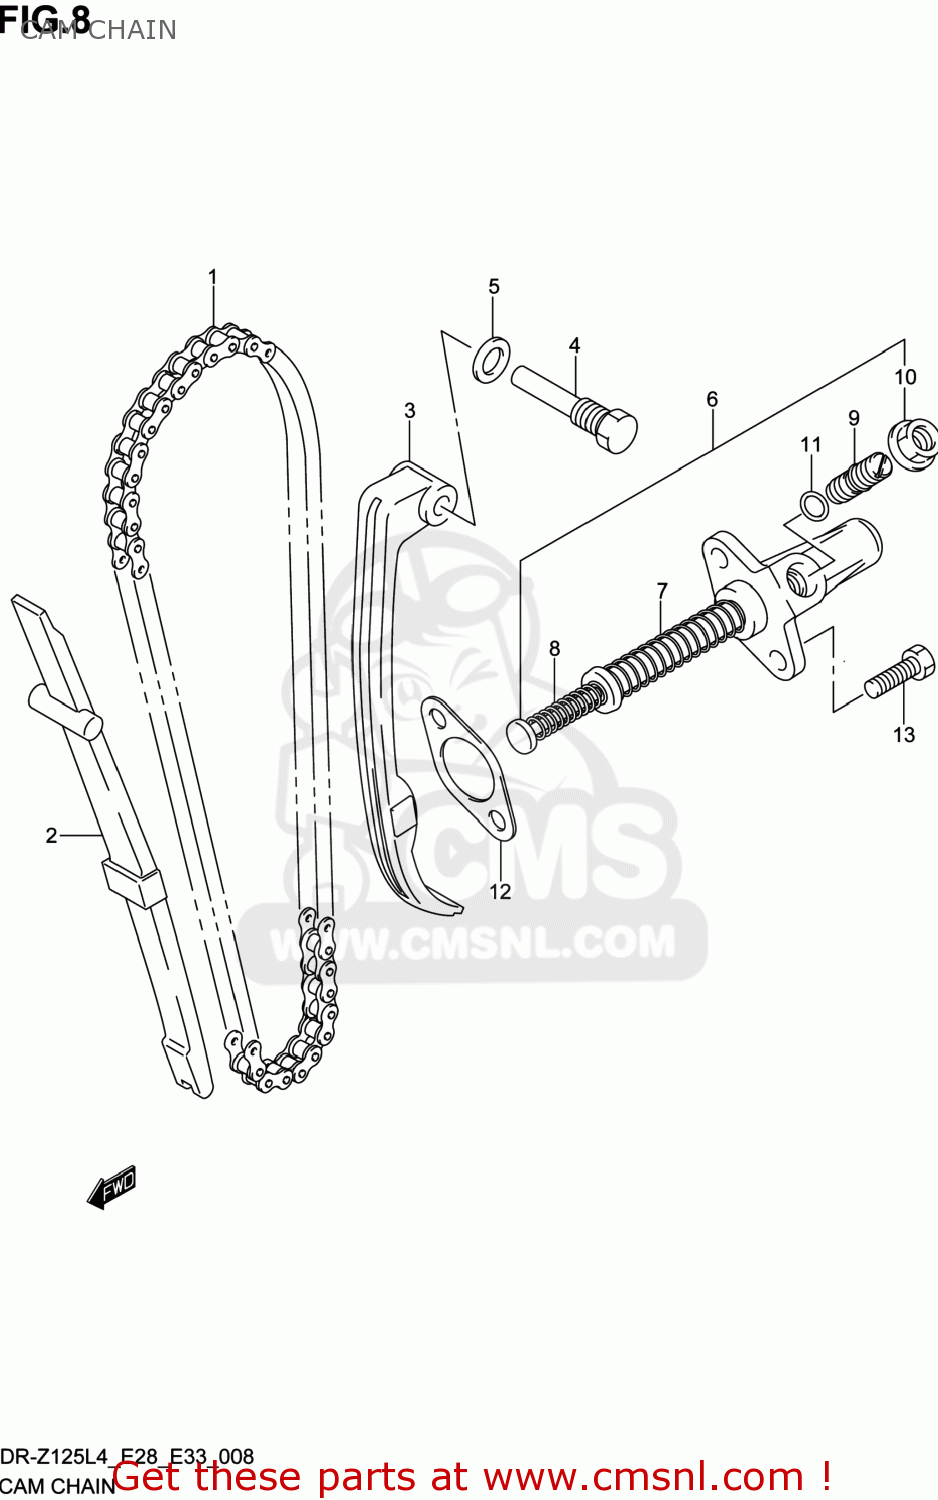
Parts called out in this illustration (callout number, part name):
1	CHAIN,CAMSHAFT DRIVE
2	GUIDE,CAM CHAIN
3	TENSIONER,CAM CHAIN
4	BOLT,CAM CHAIN TENSIONER
5	GASKET(8.2X14X1) (NAS)
6	ADJUSTER ASSY,TENSIONER
7	SPRING
8	SPRING
9	BOLT,ADJUST
10	NUT
11	O RING(D:1.9,ID:5.7)
12	GASKET,TENSIONER ADJUSTER (NAS)
13	BOLT
